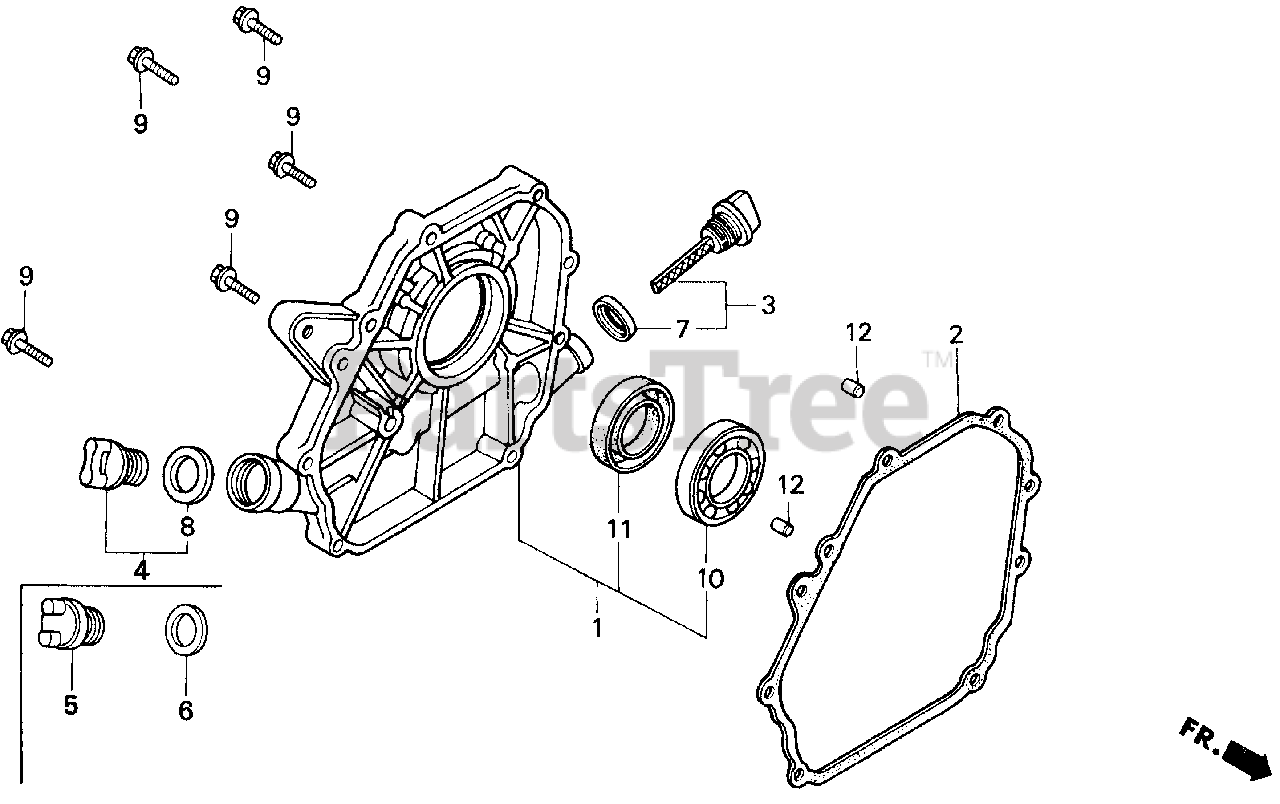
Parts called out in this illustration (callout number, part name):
1	COVER ASSY., CRANKCASE (U-TYPE)
2	GASKET, CASE COVER
3	CAP ASSY., OIL FILLER
4	CAP ASSY., OIL FILLER
5	CAP, OIL FILLER
6	GASKET, OIL FILLER CAP
7	GASKET, OIL FILLER CAP
8	GASKET, OIL FILLER CAP
9	BOLT, FLANGE (6X28)
10	BEARING, RADIAL BALL (62/22)
11	OIL SEAL (22X41X6)
12	PIN A, DOWEL (8X14)
